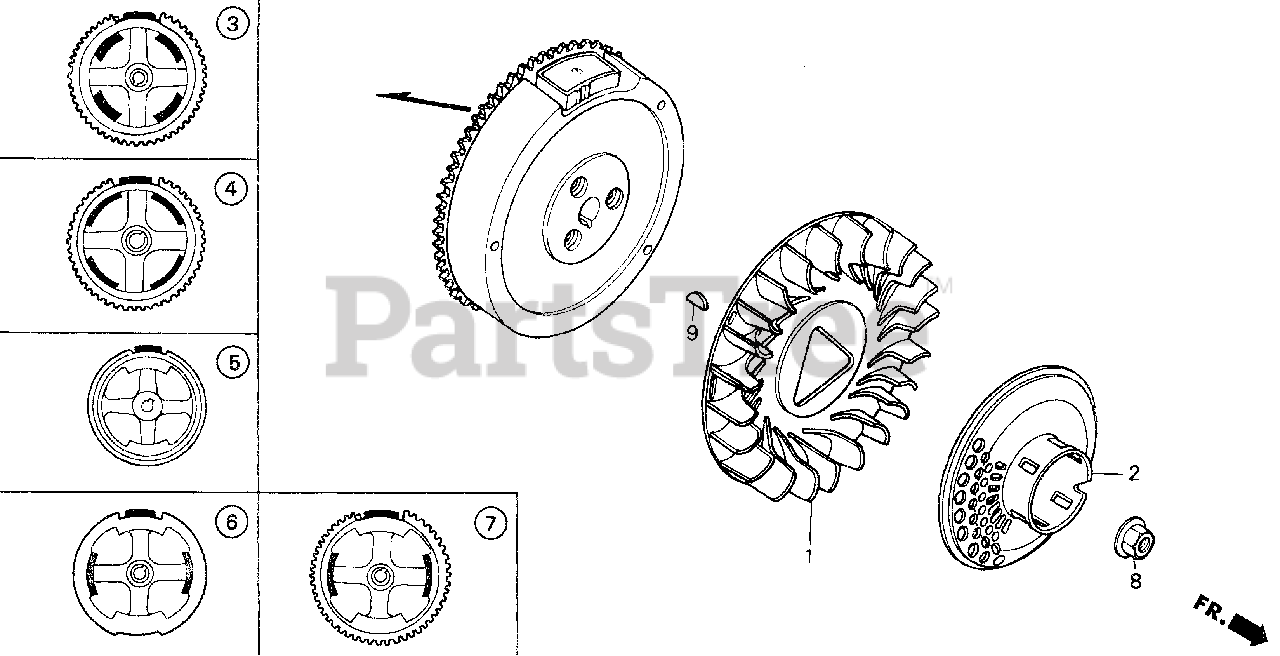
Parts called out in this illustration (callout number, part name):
1	FAN, COOLING
3	FLYWHEEL (4 POLE)
8	NUT, SPECIAL (16MM) (1)
8	NUT, SPECIAL (16MM)
9	KEY, SPECIAL WOODRUFF (25X18)
